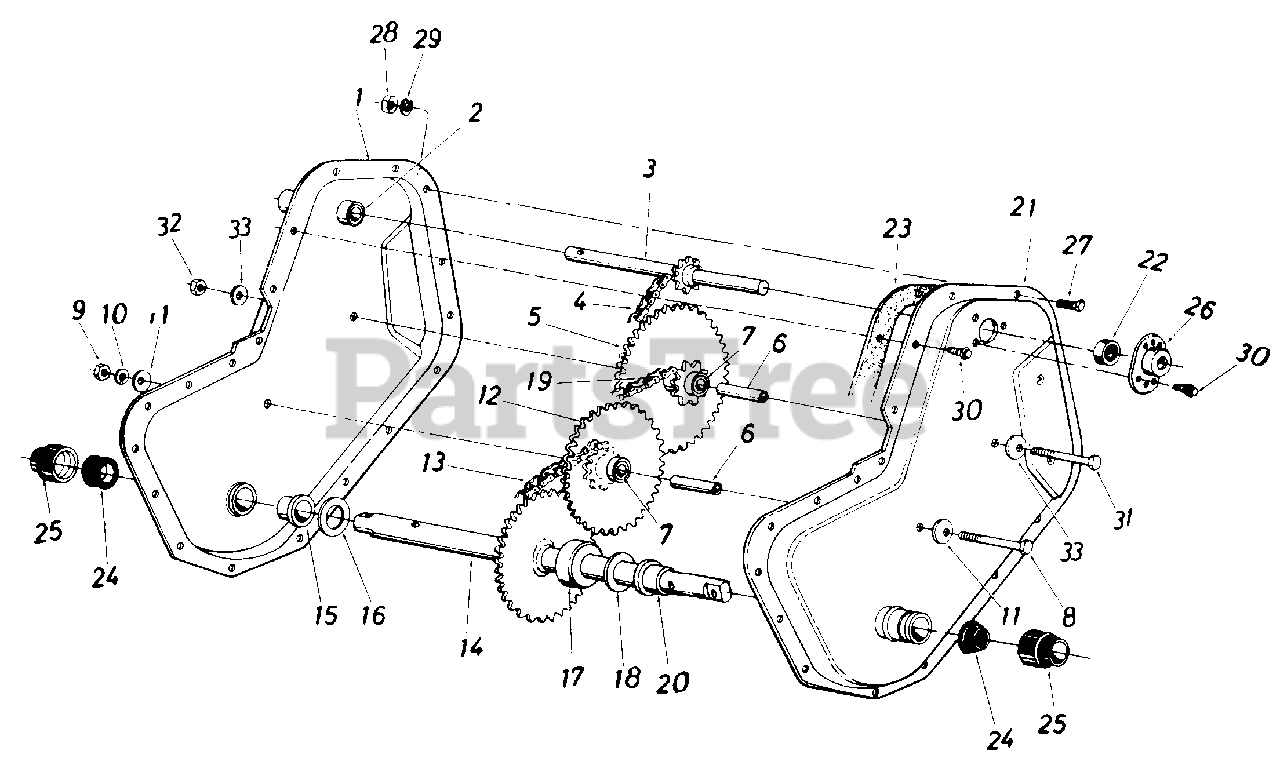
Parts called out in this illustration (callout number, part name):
1	Chain Case Half Ass'y. R.H..
2	Bearing 5/8" I.D. x .813" O.D. x 1.31" Lg.
3	Input Shaft Ass'y
4	Chain #35 3/8" Pitch x 44 Links
5	Sprocket and Hub Ass'y.
6	Bearing Inner Axle
7	Sleeve Brg. 5/8" I.D. x 3/4" O.D. x 1.50
8	Hex Bolt 3/8-24 x 2.50" Lg.*
9	Hex Ins. L-Nut 3/8-24 Thd.
10	L-Wash. 3/8" I.D.*
11	Bell-Wash. .41" I.D. x 1.13" O.D. x .03
12	Sprocket & Hub Ass'y. 9T-22T
13	#420 Chain 1/2 Pitch x 28 Links Endless
14	Wheel Shaft Ass'y
15	Flange Bearing
16	Fl-Wash. .88" I.D. x 1.5" O.D. x .03
17	Spacer 7/8" I.D. x 13/4" O.D. x.68" Lg.
18	Fl-Wash. .88" I.D. x 1.50" O.D. x .03
19	#420 Chain 1/2" Pitch x 30 Links Endless
20	Flange Bearing
23	Gasket
26	Bearing Housing
27	Hex Bolt 1/4-28 x 5/8" Lg.
28	Hex Nut 1/4-28 Thd.
29	L-Wash. 1/4" I.D.*
30	Hex Wash. S-Tap Scr. 1/4-20 x.50" Lg.
31	Hex Bolt 5/16-18 x 2.5" Lg.
32	Hex Cent. L-Nut 5/16-18 Thd.
33	Fl-Wash. 5/16" I.D.
